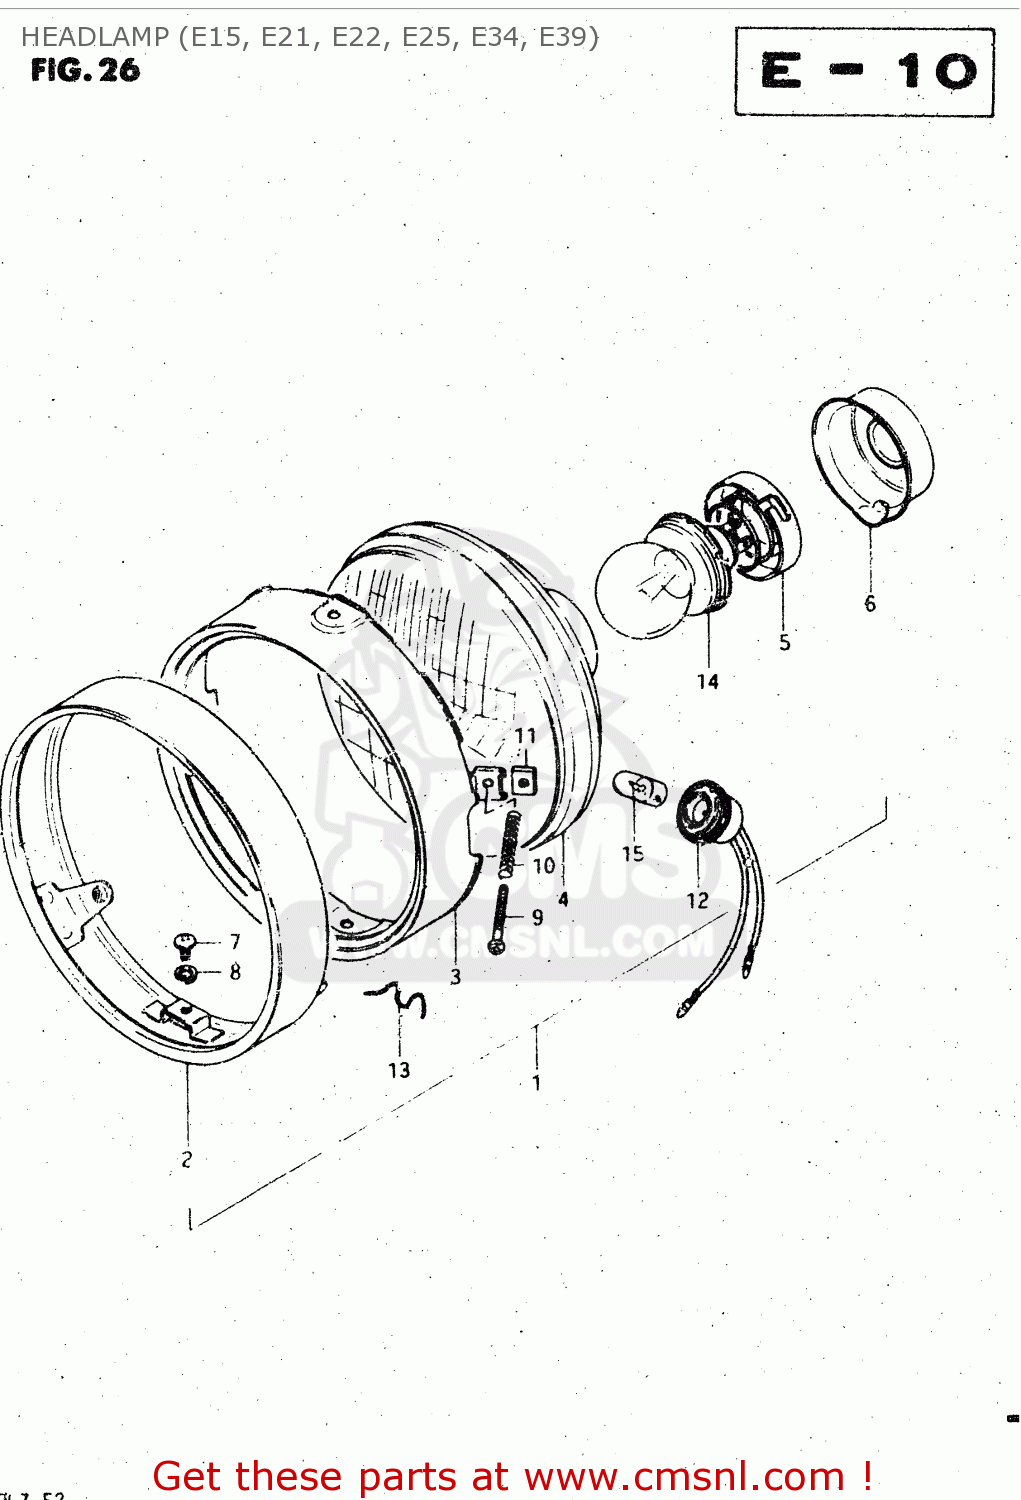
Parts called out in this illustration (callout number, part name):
1	HEADLAMP ASSY
2	RIM
3	RETAINER
4	LAMP UNIT
5	SETTER,BULB
6	COVER,HEADLAMP BULB
7	SCREW
8	LOCK WASHER
9	SCREW
10	SPRING
11	NUT
12	SOCKET
13	SPRING
14	BULB(12V45/40W)
15	BULB(12V4W)
16	SCREW(5X12)
